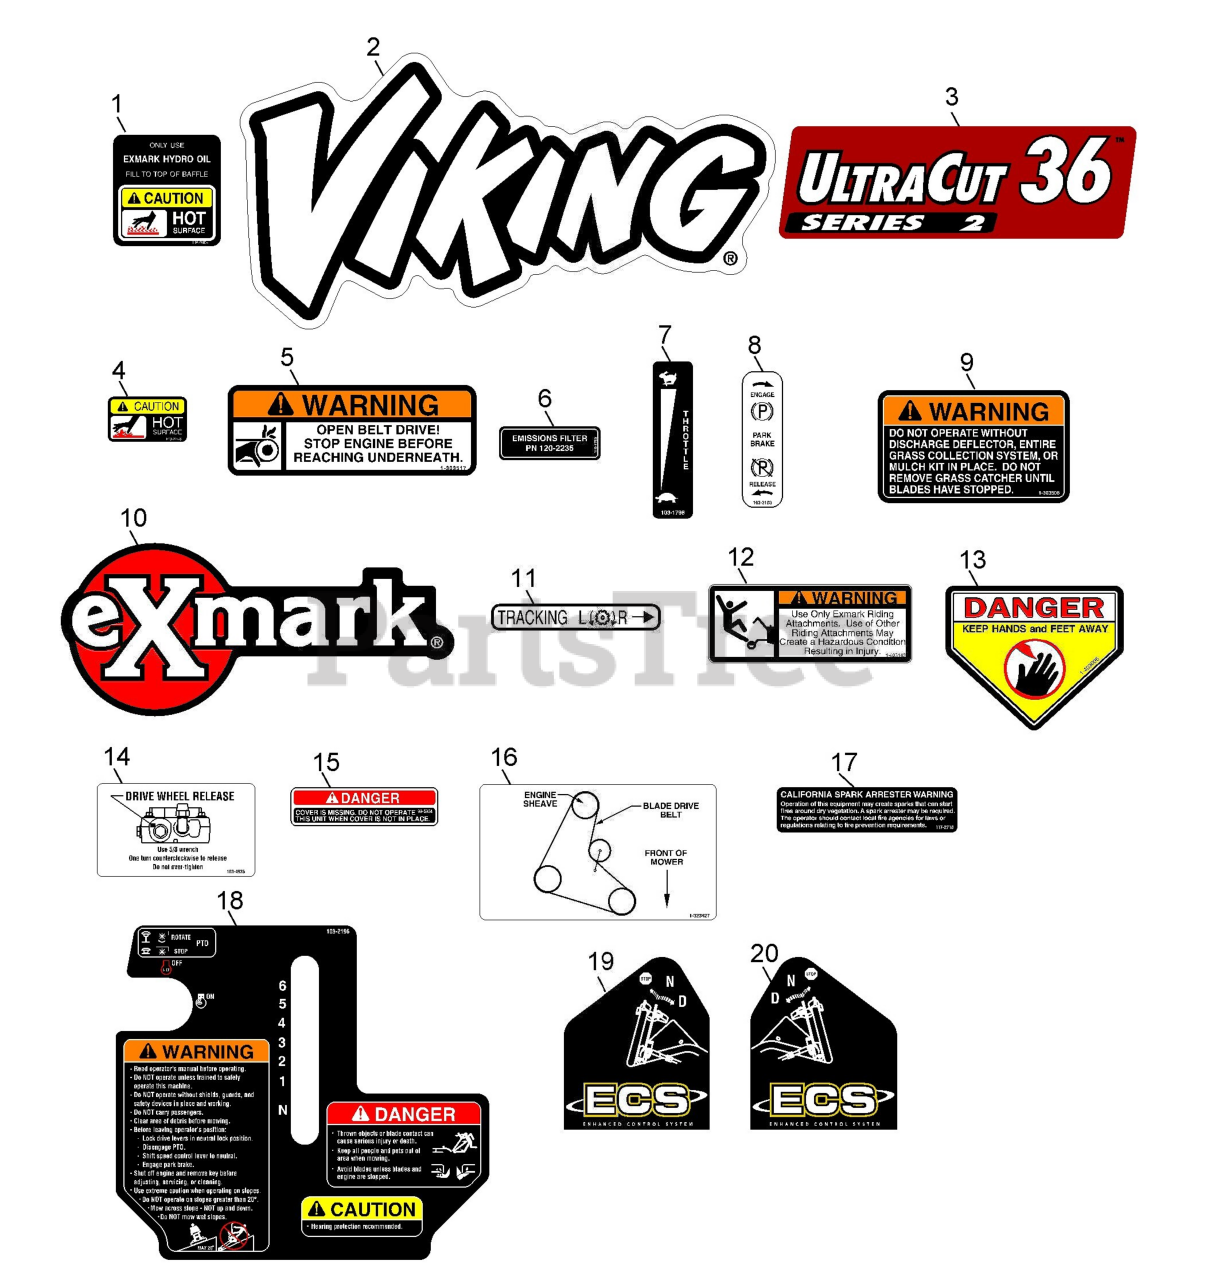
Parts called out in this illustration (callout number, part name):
1	DECAL-HYDRAULIC TANK
2	DECAL,VH MODEL
3	DECAL-ULTRACUT 36 SERIES
4	DECAL-CAUTION
5	DECAL,BELT DRIVE
6	DECAL-FILTER, EMISSIONS
7	DECAL,THROTTLE ONLY
8	DECAL-BRAKE, PARK
9	DECAL-WARNING, DISCHARGE
10	DECAL,EXMARK LOGO
11	DECAL,TRACKING ADJUST
12	DECAL,SULKY WARNING
13	DECAL-DANGER
14	DECAL,DRIVE RELEASE
15	DECAL-COVER, MISSING
16	DECAL,BELT ROUTING 32/36
17	DECAL-ARRESTER, SPARK
18	DECAL,CONSOLE VH ECS
19	DECAL,LH ECS INSTRUCTION
20	DECAL,RH ECS INSTRUCTION
